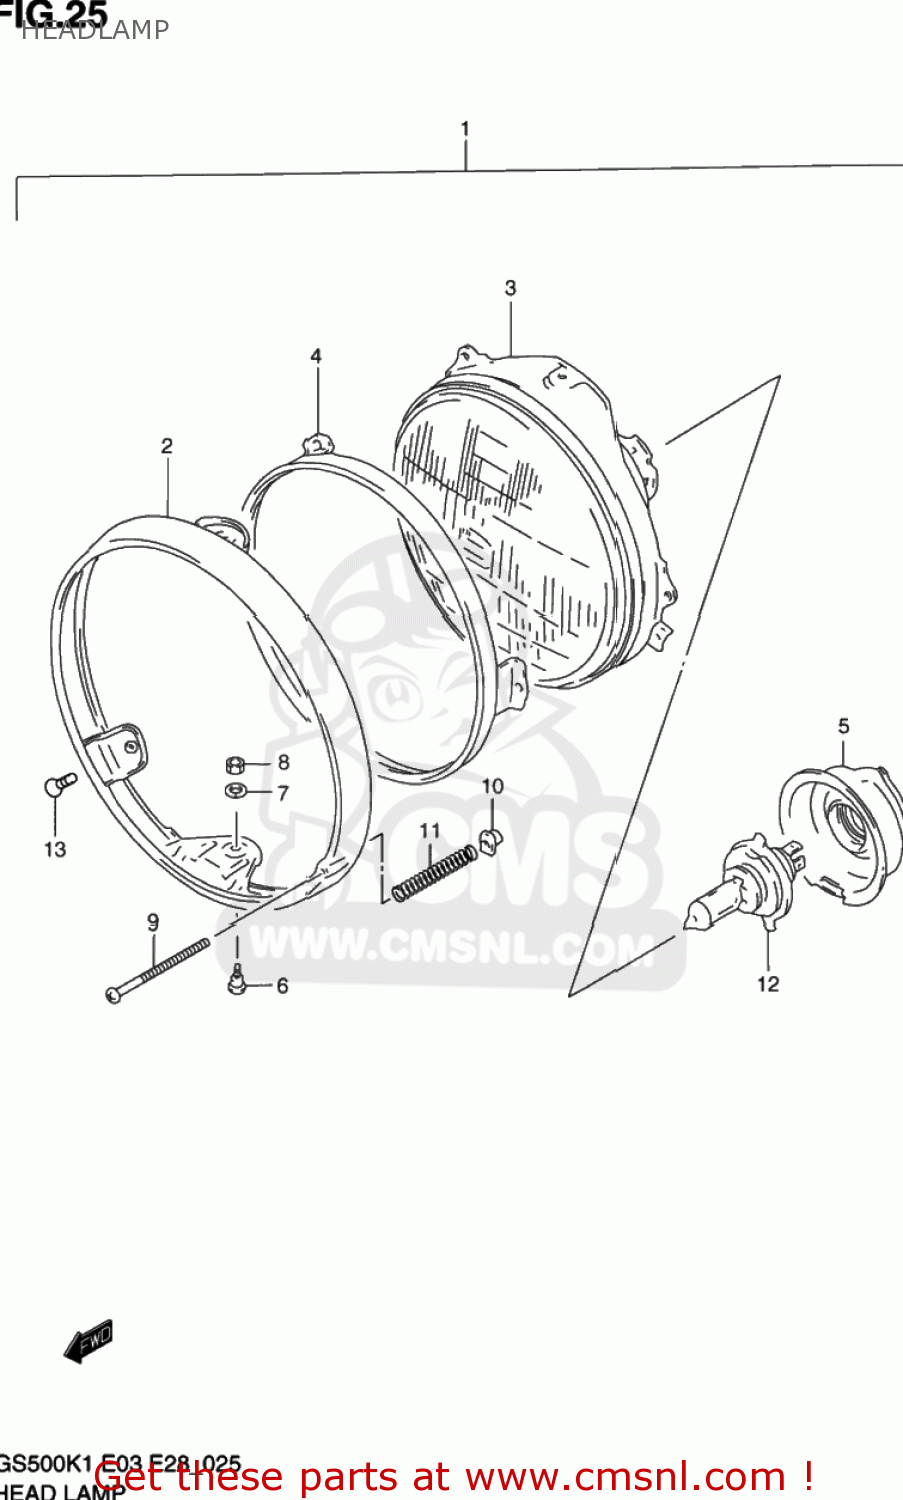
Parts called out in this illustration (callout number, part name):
1	HEADLAMP ASSY
2	RIM,HEADLAMP
3	LAMP UNIT
4	RING
5	COVER,SOCKET
6	H/LAMP LENS UNIT FITING SCRE
7	WASHER,LOCK
8	NUT
9	SCREW
10	NUT
11	SPRING,ADJUSTING
12	BULB(12V60/55W,H4)
13	SCREW(5X12)
